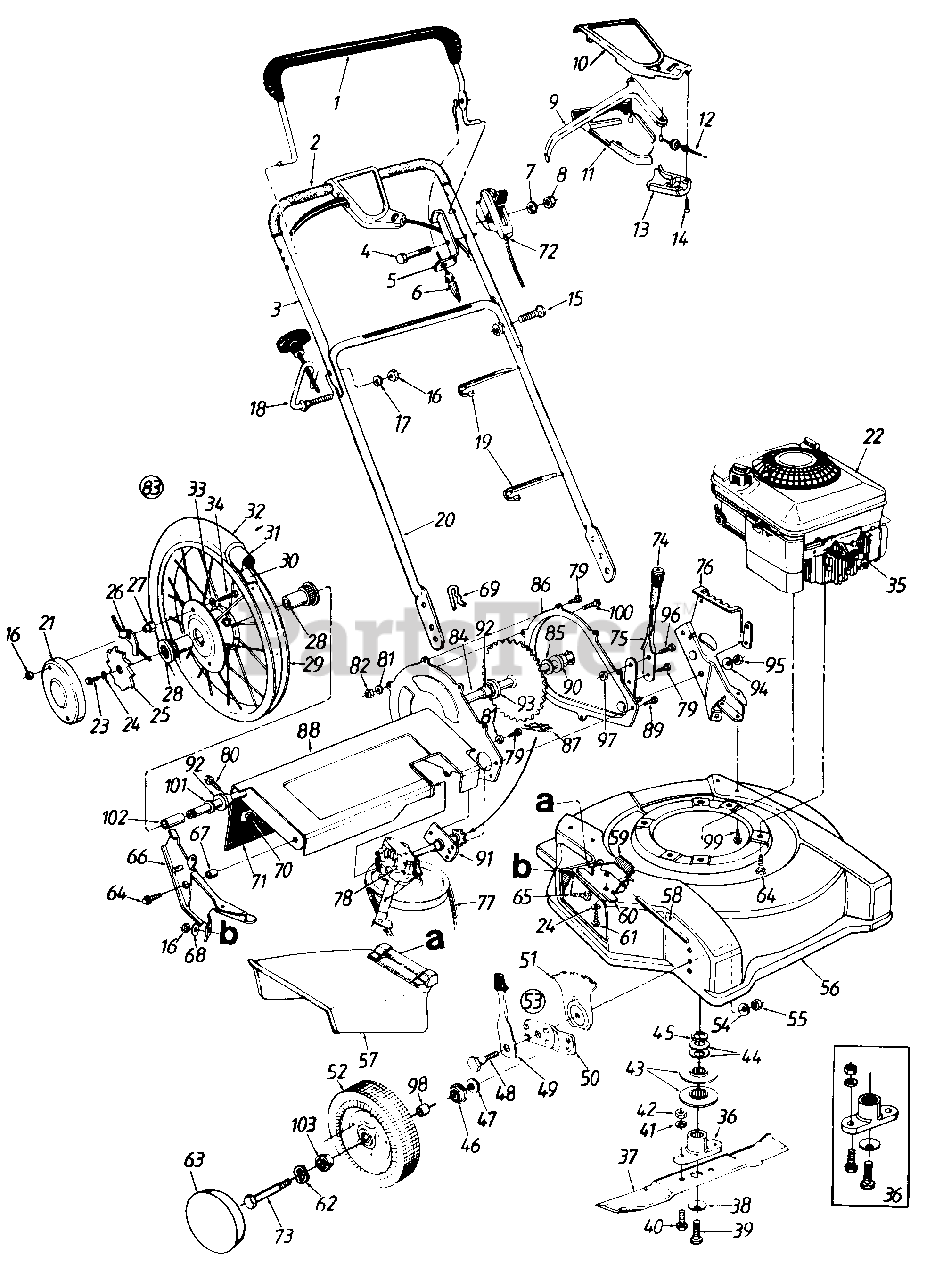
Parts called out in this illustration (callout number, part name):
1	Control Hand e Ass'y.
2	Foam Grip
3	Upper Handle
4	Hex Bolt 1/4-20 x 2.0" Lg.
5	Cable Mtg. Brkt.
6	Control Cable-36" Lg.
7	Spring Wash. .265" I.D.
8	Hex Nut 1/4-20 Thd. *
9	Control Lever
10	Control Cover Half-Upper
11	Control Cover Half-Lower
12	Self-Propelled Cable-44" Lg.
13	Cable Mounting Cap
14	Fl-"C" Sunk Hd. Tap Scr. #10 x .75" Lg.
15	Curved Carr. Bolt 5/16-18x1.38"lg.
16	Hex Nut 5/16"18 Thd.
17	L-Wash. 5/16" I.D.
18	Rope Guide Bolt
19	Cable Tie
20	Lower Handle
21	Wheel Cover
22	Engine
23	Hex Bolt 1/4-20" x .75" Lg. (Gr. 5)
24	Bell-Wash. 1/4" I.D.
25	Wheel Ratchet
26	Pawl and Spring Ass'y.
27	Special Hex Nut 5/16-18 Thd.
28	Flange Bearing .63" I.D.
29	Rim Ass'y. 16" x 2.1"
30	Rimstrip 16" x 7/8"
31	Inner Tube 16" x 2.12"
32	Chevron Tire 16" x 2.125"
33	Intern. L-Wash. 5/16" I.D.
34	Hex Bolt 5/16-18 x 1.0" (Gr. 5)
35	Spark Plug Boot
36	Blade Adapter Kit
37	22" Blade
38	Bell-Wash. .46" I.D.
39	Hex Bolt 7/16-20 x 1.5" Lg. (Gr. 5)
40	Hex Bolt 3/8-24 x 1" Lg.
41	L-Wash. 3/8" I.D.
42	Hex Nut 3/8-24 Thd.*
43	Pulley Half
44	Bell-Wash. 1.01" l.D.
45	Crankshaft Spacer
46	Ball Bearing 1/2" I.D.
47	Bell-Wash. .38" I.D.
48	Shld. Bolt .5"
49	Spring Lever Ass'y. w/Knob
51	Height Adj. Plate
52	Wheel Ass'y. Comp.
53	Height Adj. Ass'y. Comp.-F
54	Bell-Wash. 39" I.D. x 1.38"
55	Hex Nut 3/8-16 Thd.
56	22" Deck Ass'y.
57	Chute Deflector Ass'y.
58	Hinge Pin
59	Torsion Spring
60	Adapter Plate
61	Hex TT-Tap Scr. 1/4-20 x 5"
62	Wave Wash. 53" l.D. x .78"
64	Hex TT-Tap Scr. 3/8-16 x 1"
65	Carriage Bolt 5/16-18 x .62" Lg.
66	Handle Brkt. Ass'y.-R.H.
67	Spacer 383" I.D. x 503n
68	Bell-Wash. 5/16" l.D.
69	Intern. coner Pin 5/16" Dia.
70	Retaining Strip
72	Throttle Control Ass'y. Comp.-49" Lg.
73	Front Axle Bolt
75	Height Adjustment Lever
76	Handle Brkt. Ass'y.-L.H.
77	"V" Belt
78	Trans. Comp.
79	Hex B-Tap Scr. 1/4 X .38" Lg.
80	Hex AB-Tap Scr. 1/4 X .62" Lg.
81	L-Wash. 1/4" I.D.
82	Hex Nut 1/4-20 Thd.
83	Wheel Ass'y. Comp.
84	Sprocket and Axle Ass'y.
85	Fl-Wash. 635" I.D. x 1.0" O.D.
86	Chain Case and Arm Ass'y.
87	#48 Chain 1/2" Pitch x 52 Links
88	Rear Drive Support Ass'y.
89	Hex Wash. Hd. TT-Tap Scr. 1/4-20 x .5" Lg.
90	Hex Flange Brg. .631" I.D.
92	Hex Flange Brg. .631" I.D.
93	Spacer 63" l.D. x 1.25"
94	Fl-Wash. .385" I.D. x .87" O.D.
95	Hex L-Nut 3/8-24 Thd.
96	Hex Bolt 3/8-16 x .62" Lg.
97	Flanged L-Nut 3/8-16 Thd.
99	Hex B-Tap Scr. 5/16-18 x .5"
100	Hex Bolt 1/4-20 x .5" Lg.
101	Fl-Wash. .632" I.D. x .943"
102	Spacer .628" I.D. x .875"
103	Ball Bearing 3/8" I.D.
